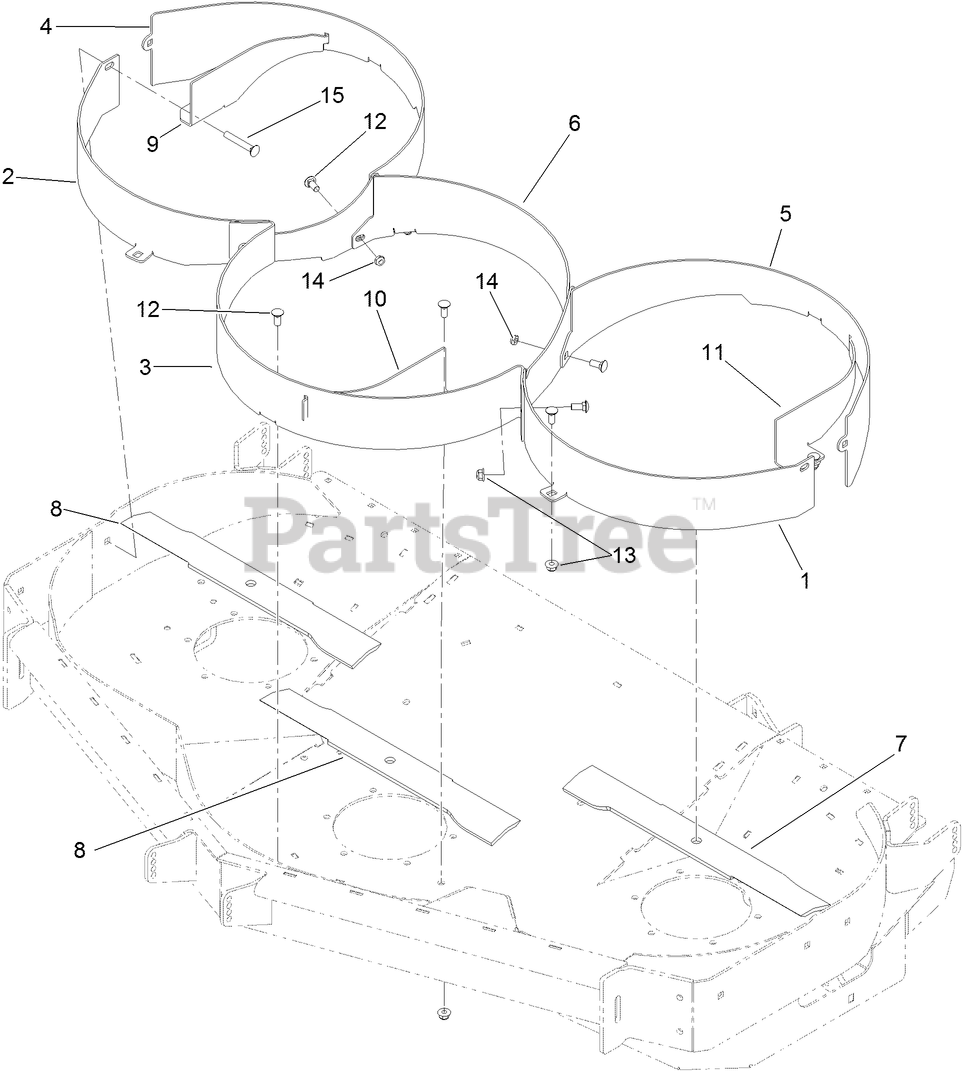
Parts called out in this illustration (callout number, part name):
1	BAFFLE-MULCH, FRONT RH
2	BAFFLE-MULCH, FRONT LH
3	BAFFLE-MULCH FRONT CENTER
4	BAFFLE-MULCH REAR LH
5	BAFFLE-MULCH REAR RH
6	BAFFLE-MULCH, REAR CENTER
7	BLADE-ROTARY, 20.5IN LOW FLOW
8	BLADE-LO FLOW, 20.5IN
9	BAFFLE-KICKER, LH
10	BAFFLE-KICKER, FRONT CENTER
11	BAFFLE-KICKER, RH
12	BOLT-CARR
13	NUT-HF, NI
14	NUT-LOCK, NI
15	SCREW-CARR
